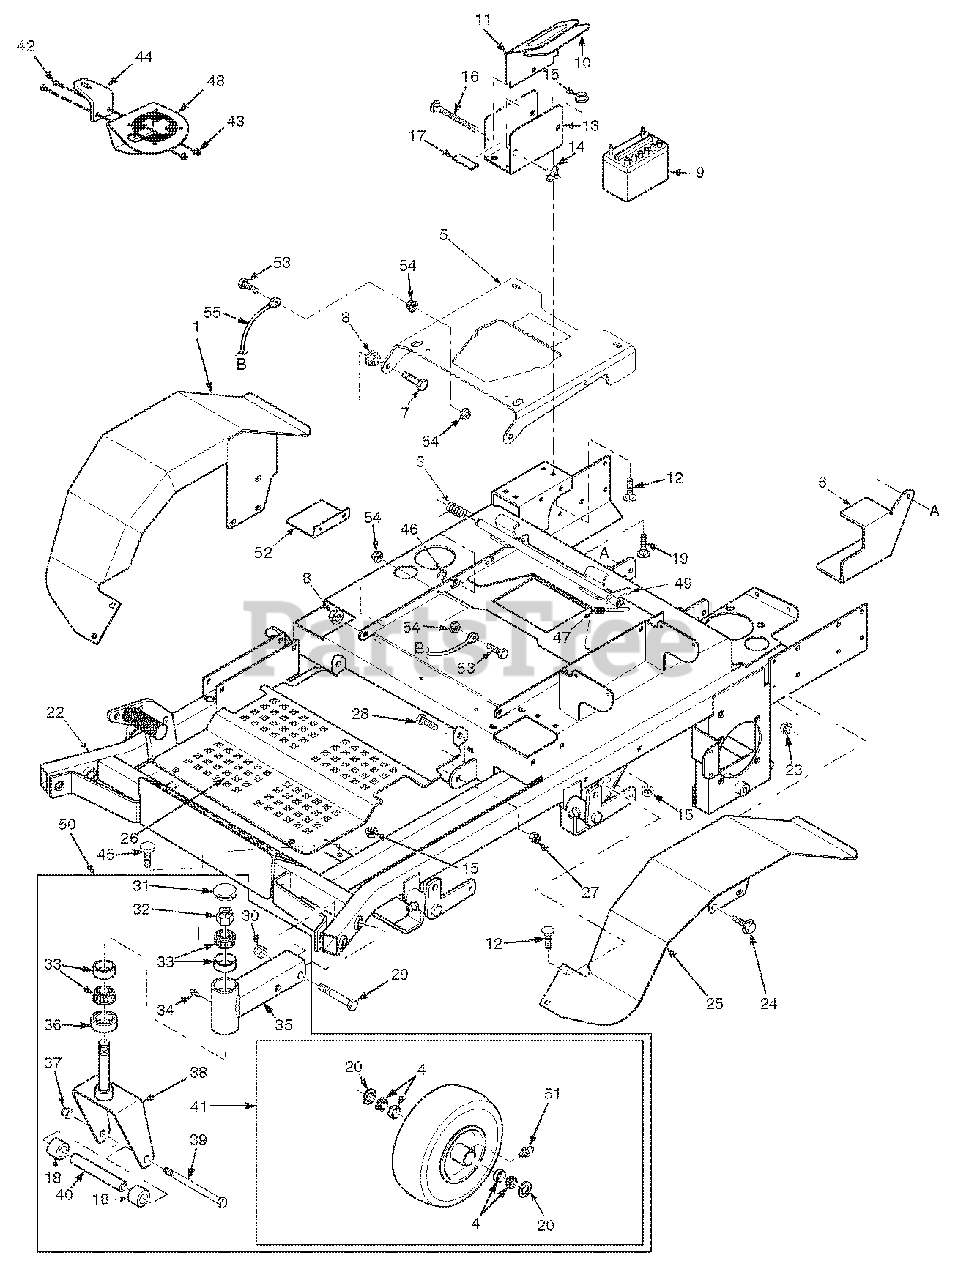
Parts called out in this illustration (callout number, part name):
1	Fender Weldment, RH
2	Bolt, Hex Head, 5/16-18 x 1, Zinc
3	Spring, Seat Latch
4	Bearing w/ Race
5	Seat Plate w/Decal
6	Guard, Fuel Line
7	Bolt, Hex Head 7/16-14 x 1-3/4"
8	Nut, 7/16-14 Serrated Flange
9	Battery (not avail. through Scag)
10	Pad, Battery Cover
11	Cover, Battery
12	Bolt, Carriage 5/16-18 x 3/4"
13	Plate, Battery Box
14	Wing Nut, 1/4-20 x 3/4"
15	Nut, Hex Serrated Flange 5/16-18
16	Bolt, Carriage 1/4-20 x 6"
17	Rubber Pad
18	Spacer, Caster Wheel
19	Bolt, Carriage 5/16-18 x 1"
21	Locknut, 3/8-16, Elast. Stop
22	Main Frame w/Decals
23	Nut, Hex Serrated Flange 3/8-16
24	Screw, Hex Serrated Flange 3/8-16 x 1"
25	Fender Weldment, LH
26	Foot Plate
27	Nut, Hex Elastic Stop 3/8-16
28	Bolt, Hex Head 3/8-16 x 1"
29	Bolt, Hex Head 5/8-11 x 4"
30	Nut, Hex Elastic Stop 5/8-11
31	Cap, Grease
32	Nut, Hex Elastic Stop 1.0-14
33	Bearing W/Race
34	Plug, 1/4-28 THD Form
35	Extention Weldment, Caster 52V (LH)
35	Extention Weldment, Caster 52V (RH)
35	Extention Weldment, Caster 61V (LH)
35	Extention Weldment, Caster 61V (RH)
36	Seal, 2.00" OD. x 1.625" Bore
37	Nut, Hex Elastic Stop 1/2-13
38	Yoke Weldment, Caster (52V)
38	Yoke Weldment, Caster (61V)
39	Bolt, Hex Head 1/2-13 x 7-1/2" (52V)
39	Bolt, Hex Head 1/2-13 x 9-1/2" (61V)
40	Sleeve, Caster Wheel (52V)
40	Sleeve, Caster Wheel (61V)
41	Wheel Assy, 52V
41	Wheel Assy, 61V, 72A
42	Bolt, Hex Head 1/4-20 x 3/4"
43	Bolt, Hex Head 1/4-20 x 3/4"
44	Mounting Bracket, STT Cup Holder
45	Bumper, Rubber
46	Retaining Ring, .625" Ext. "E"
47	Grip, Seat Latch
48	Cup Holder Assembly
49	Lever Assembly, Seat Release
50	Caster Wheel Assembly 52V (LH)
50	Caster Wheel Assembly 52V (RH)
50	Caster Wheel Assembly 61V (LH)
50	Caster Wheel Assembly 61V (RH)
51	Grease Fitting
52	Cover, Fuel Tank Opening
53	Bolt, Hex Head 1/4-20 x 1-1/4"
54	Nut, Serrated Flange 1/4-20
55	Cable, Seat Stop
